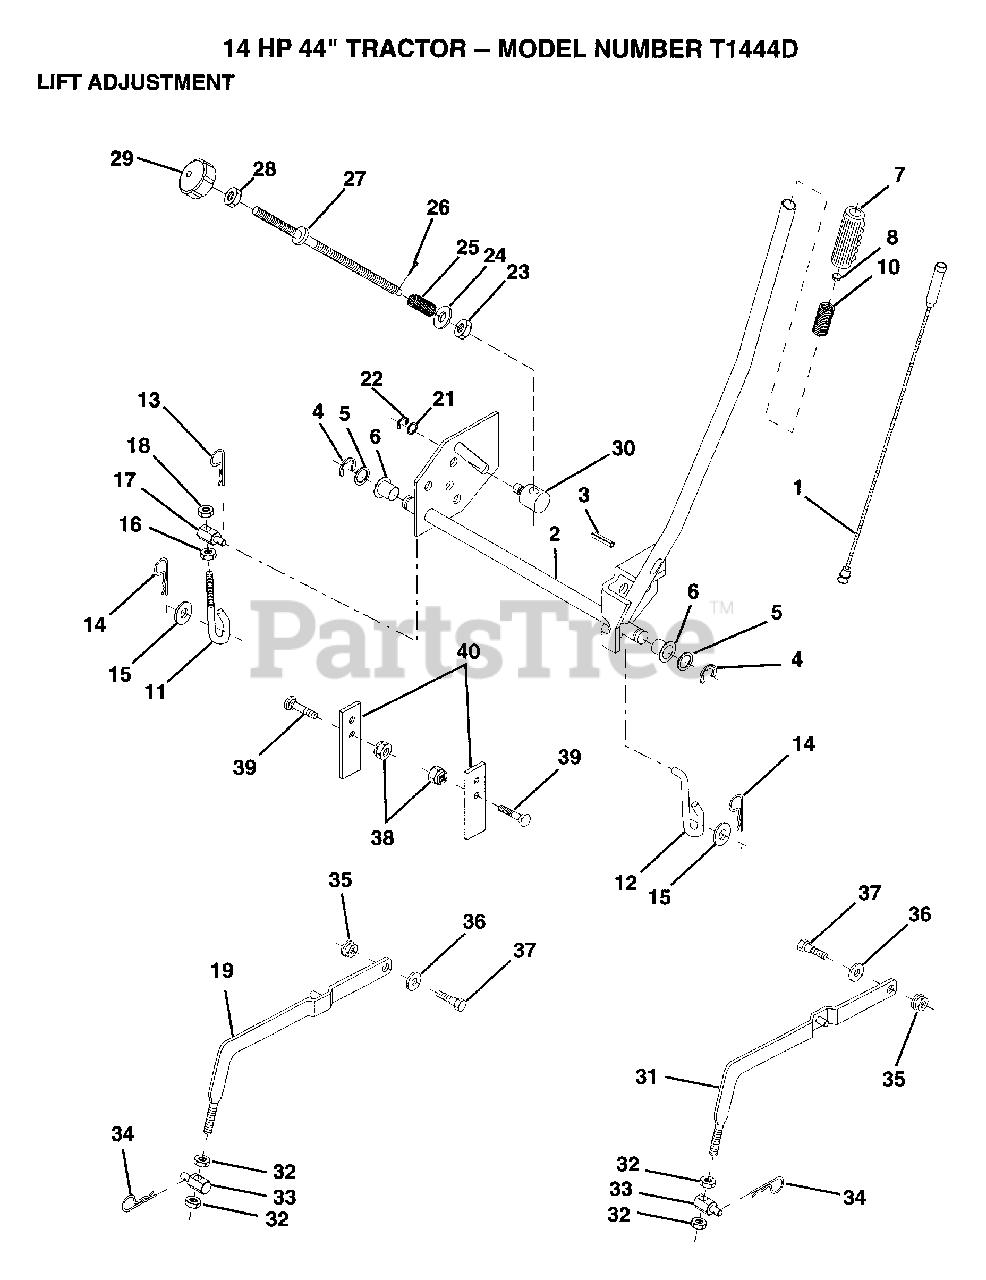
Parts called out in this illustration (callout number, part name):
1	WIRE ASM
3	PIN-GROOVE LT
5	WASHER
6	NYLON BEARING
7	GRIP
11	PIVOT PIN T
12	LIFT LINK LT
14	SPRING.RETAINER
16	NUT
19	LH SUSP ARM ASM
21	WASHER
22	KLIP RING
23	NUT T
24	WASHER
25	SPRING T
28	NUT
29	KNOB INF 3/8-16
30	TRUNION LT
31	RH SUSP ARM ASM
32	NUT
34	SPRING H
35	NUT SPECIAL T
36	WASHER T
37	"BOLT, SHOULDER LT"
40	UPSTOP
